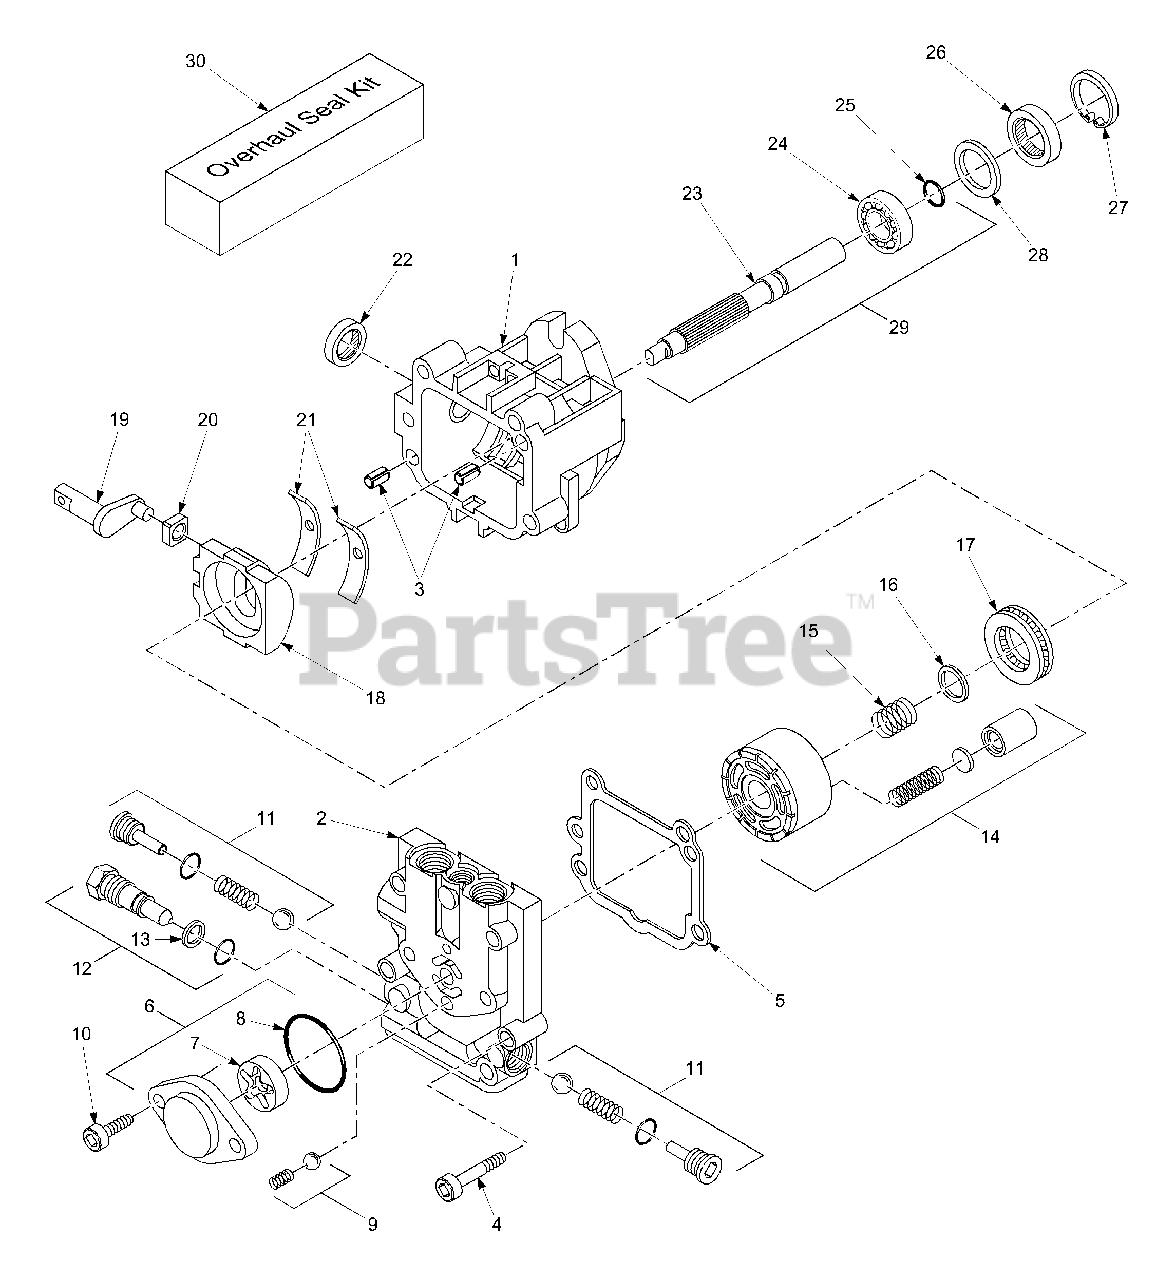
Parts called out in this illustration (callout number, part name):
1	Housing Kit
2	End Cap
3	Straight Headless Pin
4	Hex Head Screw 5/16-18x1.0
5	End Cap O-Ring
6	Charge Pump Kit
7	Gerotor Assembly
8	O-Ring, Charge Pump Cover
9	Charge Relief Valve Kit
10	Socket Head Screw
11	Check Valve Kit
12	Bypass Valve Kit
13	Backup Ring
14	Cylinder Block Kit
15	Block Spring
16	Block Thrust Washer
17	Roller Thrust Bearing
18	Swash Plate
19	Trunnion Arm
20	Guide Slot
21	Cradle Bearing
23	Pump Shaft
24	Ball Bearing
25	Retaining Ring
27	Retaining Ring
29	Shaft Kit
30	Overhaul Seal Kit
